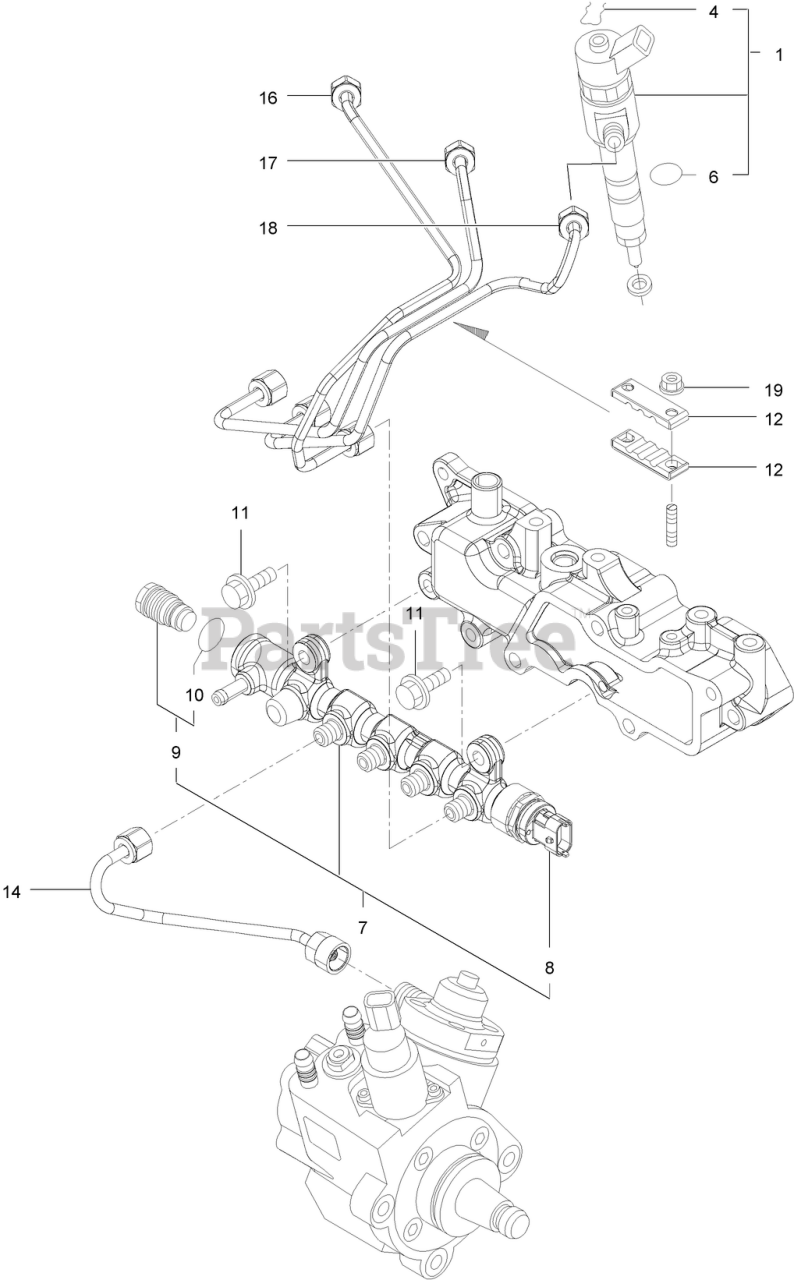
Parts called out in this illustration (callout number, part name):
1	INJECTOR ASM
4	RING, RETAINING
6	O-RING
7	RAIL ASM
8	SENSOR-PRESSURE, RAIL
9	VALVE ASM
10	O-RING, PLV4
12	RETAINER
14	RAIL IN PIPE ASM
16	INJECTION PIPE ASM
17	INJECTION PIPE ASM
18	INJECTION PIPE ASM
